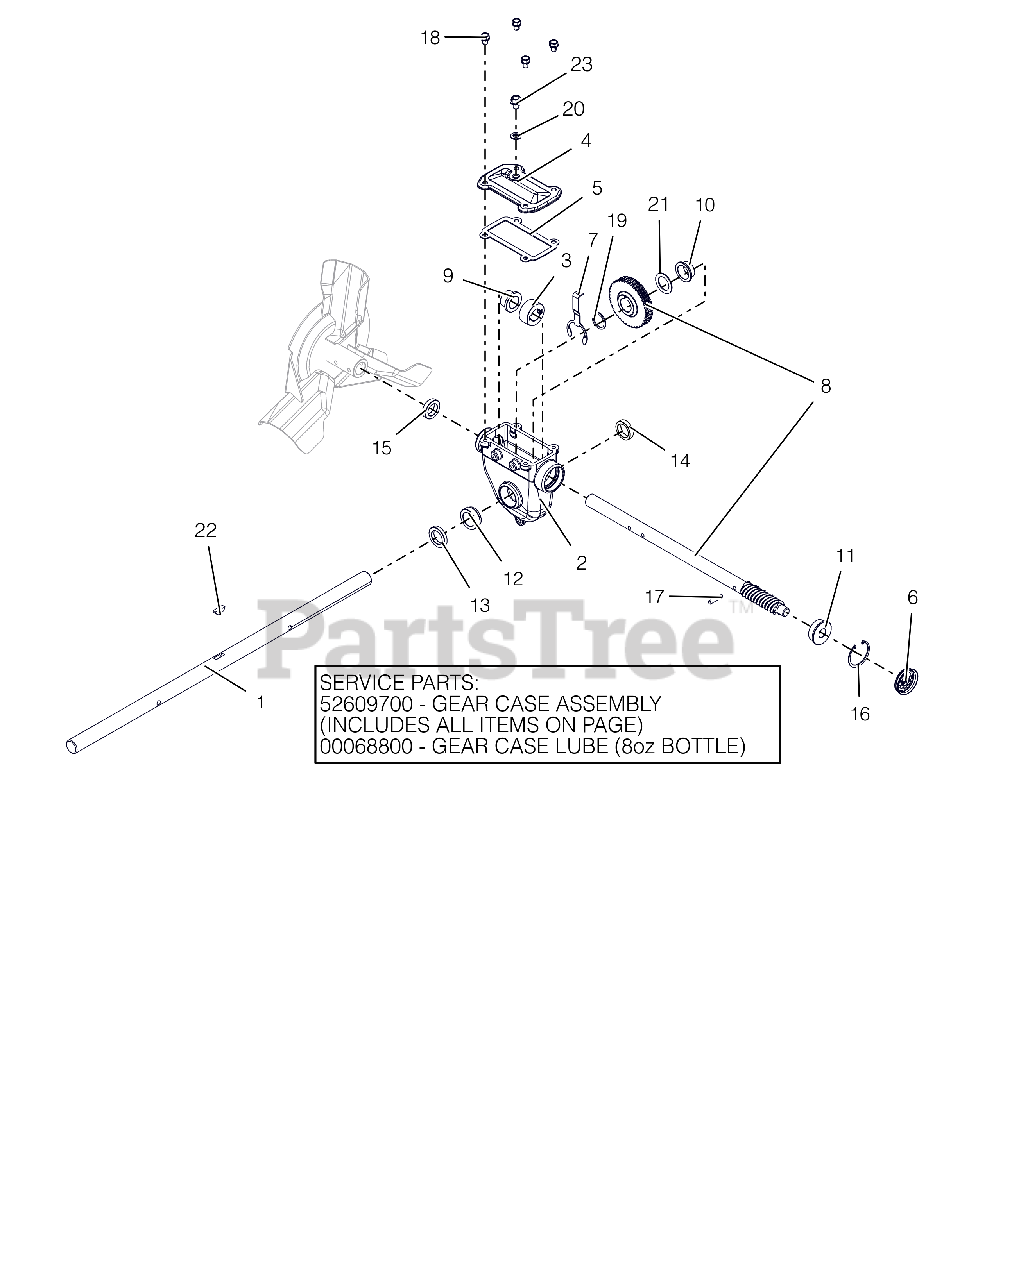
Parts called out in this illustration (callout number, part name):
1	SHAFT, RAKE-28"
2	GEARCASE, LARGE MACHINED
2	GEAR CASE, 28" IRON PRO TOP-LD
2	ARIENS L3 LUBE, 8 OZ BOTTLE
3	THRUST COLLAR, .875"ID SLIPFIT
4	COVER, TOP - LARGE IRON
5	GASKET, TOP - LARGE GEARCASE
6	COVER, GEAR CASE 1.75"
7	BUSHING RETAINER, LARGE
8	ASSY, WORM SHAFT & GEAR
9	BSHG-FLG .879X1.128X.75X1.45
10	BSHG-FLG 1.006X1.128X.555X1.45
11	BSHG-FLG .628X1.503X.58X1.725
12	BSHG-FLG LARGE, RIGHT
13	SEAL-OIL .999X1.500X.250 TBC29
14	SEAL-OIL .999X1.375X.312 TBC29
15	SEAL-OIL .873X1.375X.312 TBC29
16	RG-RTNG-INT 1.750X.062
17	PIN-STR .250X1.12 6150
18	BOLT, SEMS .31-18X.50 GR5 YWZC
19	WSHR-FL-STL 1.010X1.250X.068YZ
20	WSHR-BND-SEAL .38X.75X.11 GALV
21	WSHR-FL-STL 1.010X1.505X.062YZ
22	KEY-WDRF .25X.875 HRD #A
23	@SCR-ROLOK .38-16X.50 HWH YWZC
